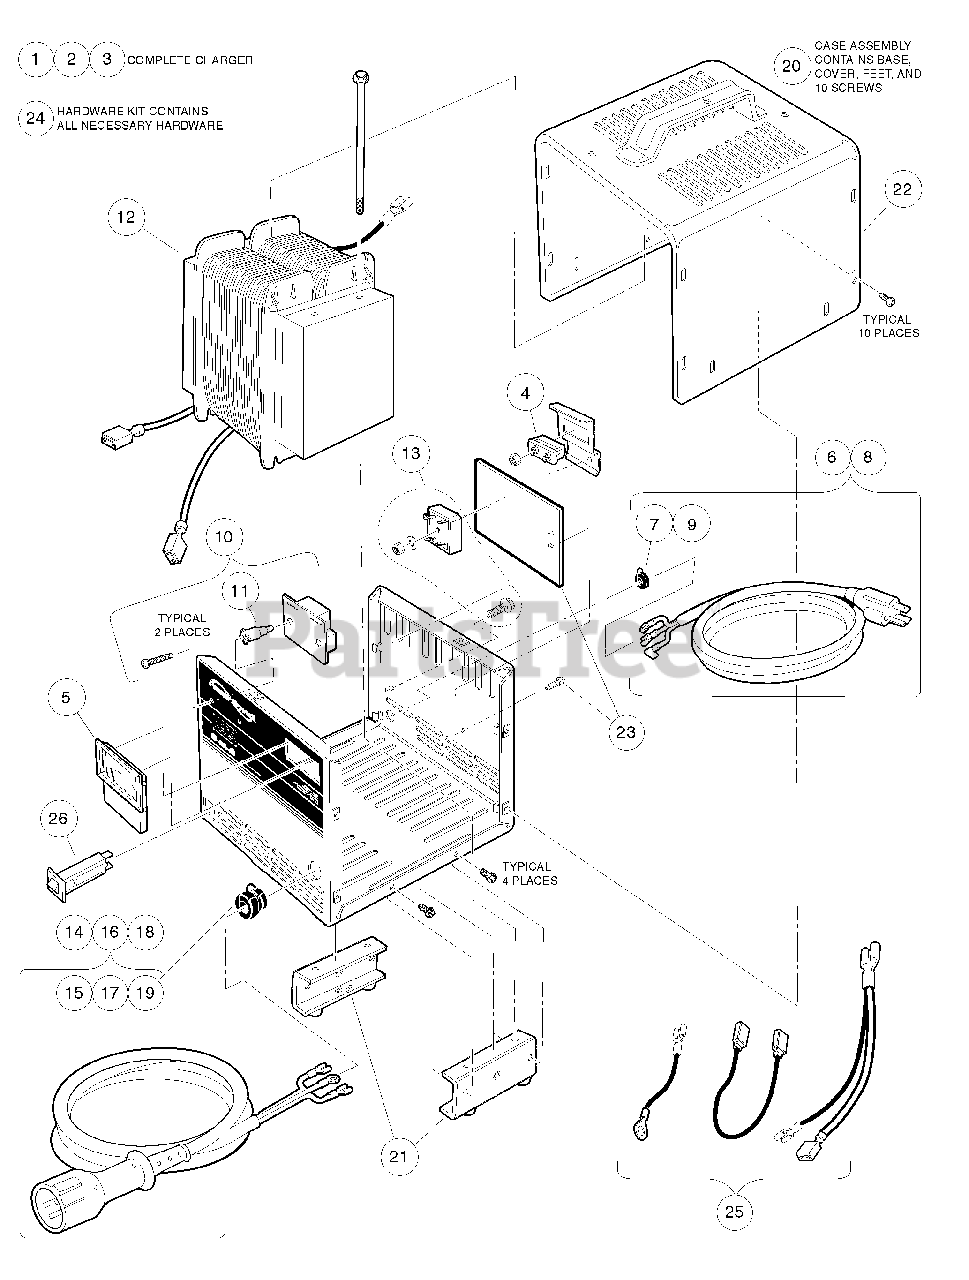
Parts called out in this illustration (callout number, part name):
1	Charger, Pd3, 9Dc/6'Ac'
2	Charger, Pd3, 12Dc/9'Ac'
3	Charger, Pd3, 20Dc/9'Ac'
4	PD2 Fuse Asm
5	PD2 Ammeter
6	Kit, PD3 Cordset - AC 80"
7	PD2 AC Cord Bushing
8	Kit, PD3 Cordset, - AC 114"
9	PD2 AC Cord Bushing
10	Asm, PD3 Board Relay
11	PD3 Plastic Stand-Offs
12	PD3 Transformer
13	Kit, PD3 Diode Bridge
14	PD3 Cordset - DC 113"
15	Bushing, DC Cord
16	PD3 Cordset - DC 154"
17	Bushing, DC Cord
18	PD3 Cordset - DC 205"
19	Bushing, DC Cord
20	Asm, PD3 Case
21	Asm, PD3 Legs
22	PD3Case Top
23	Kit, PD3 Heat Sink
24	Kit, PD3 Hardware
25	Kit, PD3 Wires
26	Circuit Breaker, 15-Amp/120-Volt
